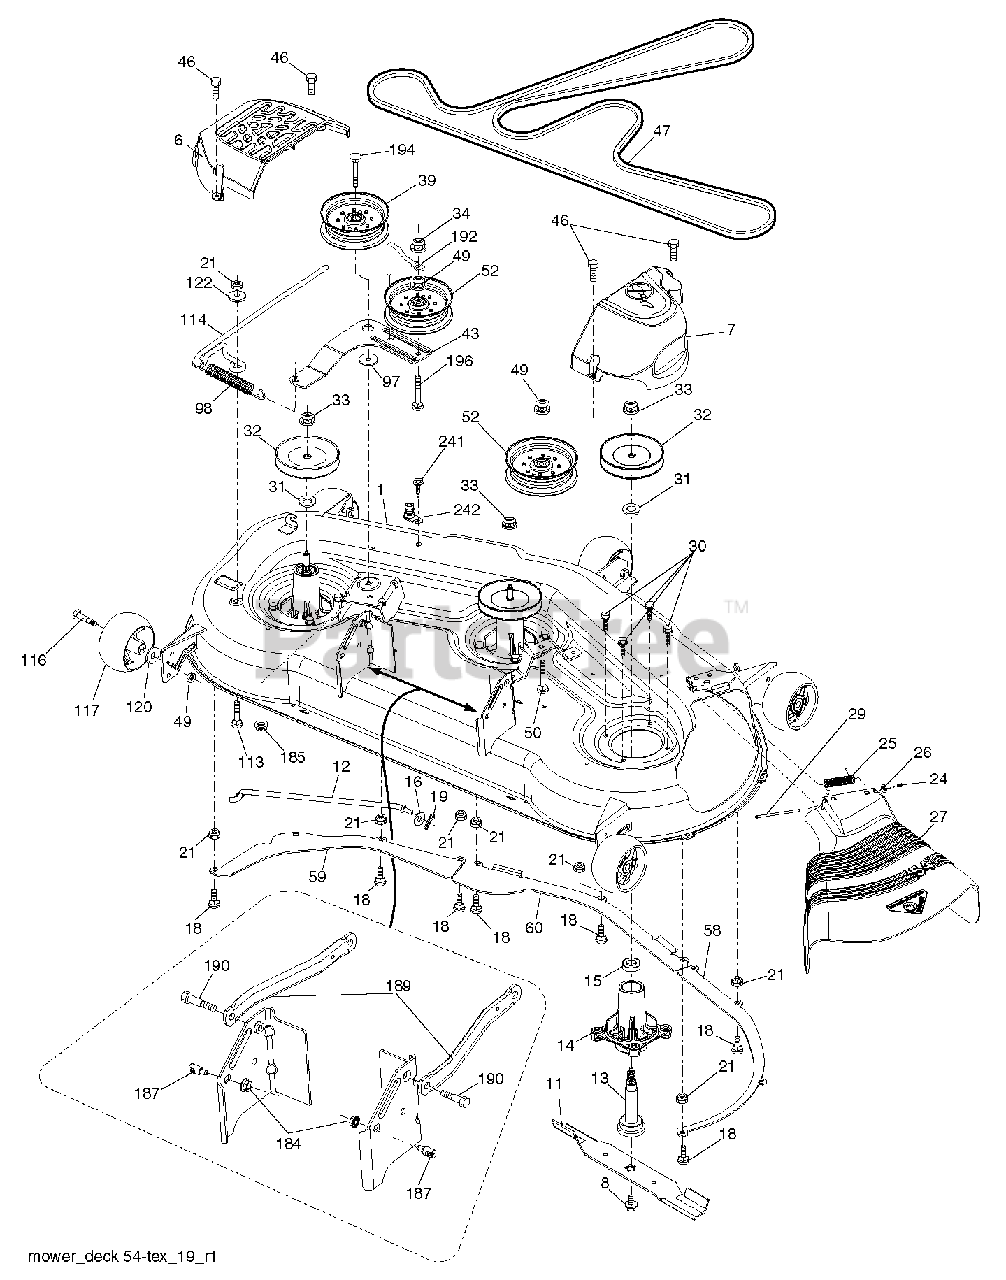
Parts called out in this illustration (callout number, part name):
1	DECK.WELDMENT.54"MS-666.BLUE
6	COVER.MANDREL.LH.54"20
7	COVER.MANDREL.RH.54.20
8	BOLT.WASHER.ASM.7/16-2
11	BLADE, BAGGING 54"
12	ROD.ANTI.SWAY.48/54"TE
13	SHAFT ASM MANDREL
14	HOUSING MANDREL
15	BEARING
18	BOLT
19	PIN.COTTER.5/16.BOW TI
24	CAP-SLEEVE LT
26	NUT PUSH M
29	ROD.HINGE
30	SCREW, WASHER HEAD
31	WASHER.SPACER.MANDREL
33	NUT.FLANGE.LOCK.TOP
34	LOCKNUT
39	PULLEY.IDLER.4.50/HUB SPECIAL
43	ARM.IDLER
46	SCREW.1/4-20X5/8
47	BELT.DRIVE.54."2006
58	BAFFLE.RIGHT.54"
59	BAFFLE.LEFT.54"
60	BAFFLE CENTER 54" MOWER
98	SPRING, DECK DRIVE
113	BOLT CRT
114	ROD TENSION RELIEF
116	BOLT.SHOULDER.3/8-16X3-5/8
117	WHEEL. GUAGE RALLY
120	WASHER
122	BUSHING.RELIEF.TENSION
184	NUT LOCK HEX FLANGE 5/16-18
185	NUT.LOCK.FLANGE.7/16
187	STUD.FASTNER.W/ANTI-ROTATE
189	ARM.SUSPENSION.MOWER
190	BOLT.SHOULDER
192	KEEPER.BELT.IDLER.54"T
242	PORT.WASHOUT
